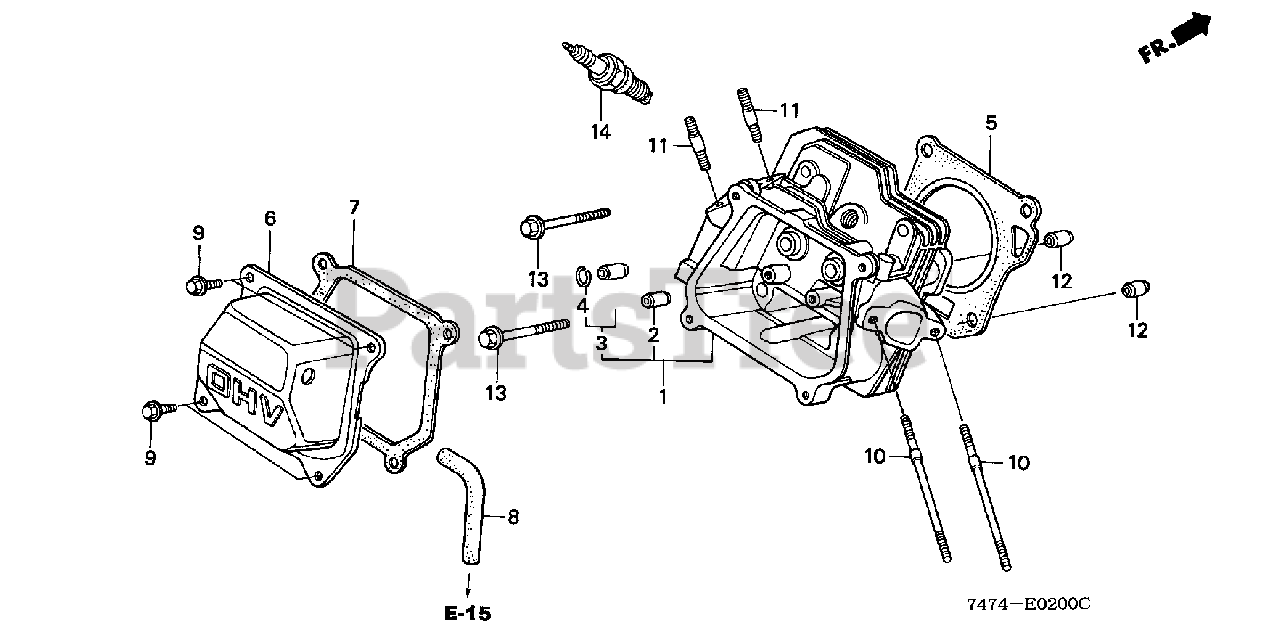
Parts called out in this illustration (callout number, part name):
1	CYLINDER HEAD
2	GUIDE, VALVE (OS) Use up to Engine SN 2401552.
2	GUIDE, VALVE (OS)
3	GUIDE, EX. VALVE (OS)
4	CLIP, VALVE GUIDE
5	GASKET, CYLINDER HEAD
6	COVER, HEAD
7	GASKET, CYLINDER HEAD COVER
8	TUBE, BREATHER
9	BOLT, FLANGE (6X13)
9	BOLT, FLANGE (6X12) (CT200)
10	BOLT, STUD (6X109)
11	BOLT, STUD (8X32)
12	PIN A, DOWEL (10X16)
13	BOLT, FLANGE (8X60)
14	SPARK PLUG (BPR5ES) (NGK)
14	SPARK PLUG (W16EPR-U) (DENSO)
